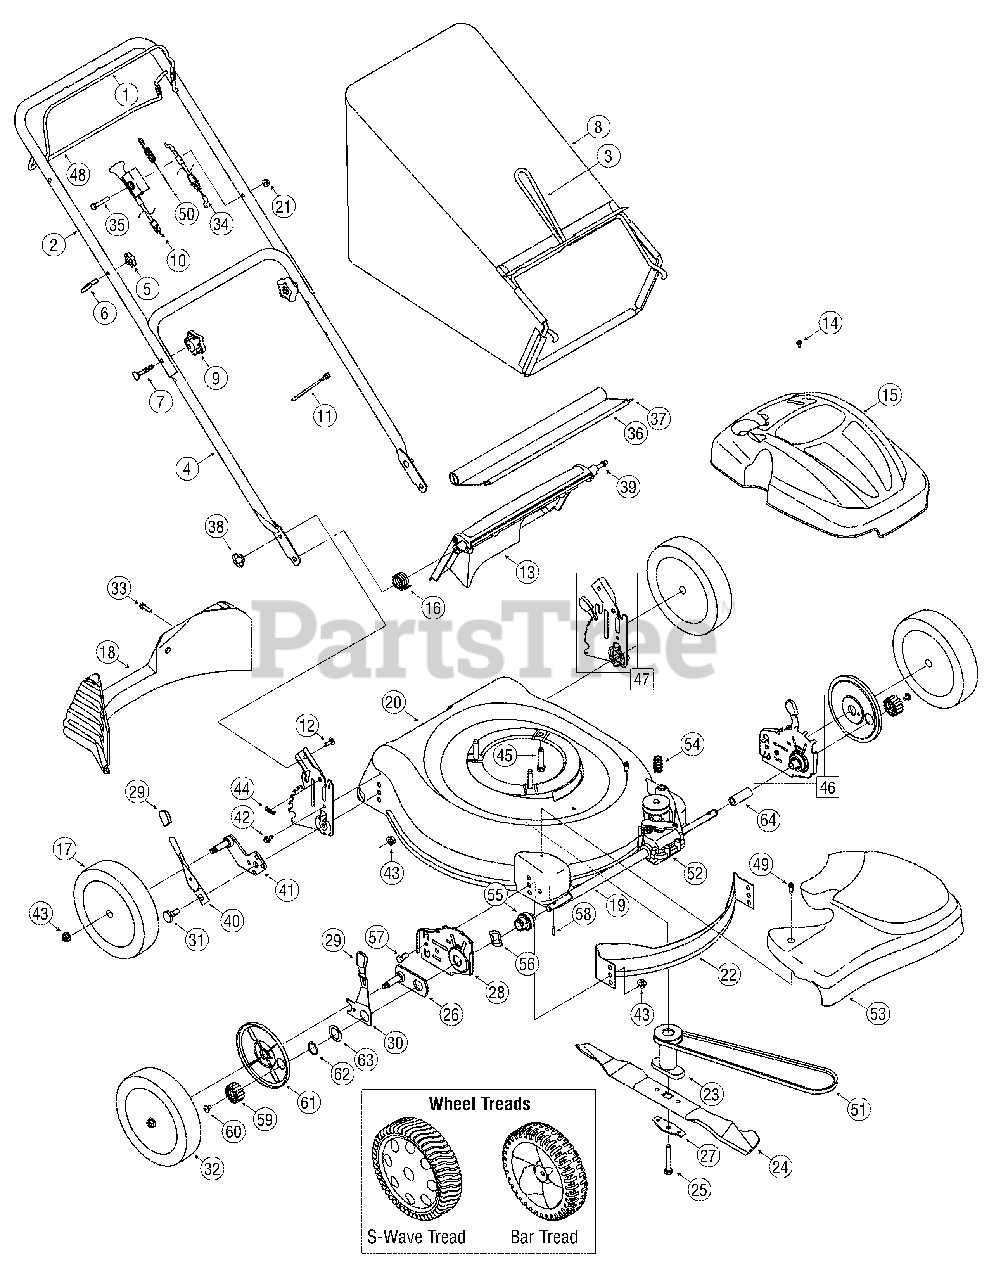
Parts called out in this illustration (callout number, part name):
5	Wing Nut
6	Rope Guide
7	Carriage Bolt ,5/16-18 x 2
8	Grass Bag Assembly
9	Star Knob
10	Choke Cable
11	Cable Tie
12	Carriage Bolt ,1/4-20
13	Rear Discharge Door
14	Screw, Machine, M-4 x 10
15	Engine Shroud
16	Torsion Spring - RH
17	Rear Wheel, 8 x 1.8, Bar
18	Rear Baffle
19	Sleeve Spacer - RH
21	Flange Lock Nut, 1/4-20
22	Front Baffle
23	Blade Adapter w/Pulley
24	21" Mulching Blade
25	Hex Bolt , 3/8-24 x 2.5
26	Pivot Plate Assembly
27	Blade Bell Support
28	Height Adjustment Plate - RH
28	Height Adjustment Plate - LH
29	Adjustment Lever Knob
30	Front Lever - RH
30	Front Lever - LH
31	Shoulder Screw
32	Front Wheel, 8 x 1.8, Bar
33	Screw, 1/4-15 x 1.000
34	Control Cable - 48"
35	Screw, 1/4-20 x 1.50
36	Trailshield
37	Trailshield Wire
38	Wing Nut, 1/4-20
39	Rear Door Pivot Rod
40	Spring Lever
41	Pivot Arm Assembly - RH
41	Pivot Arm Assembly - LH
42	AB Screw
43	Flange Lock Nut, 3/8-16
44	Hairpin Clip
45	TT Sems Screw, 3/8-16 x 1.00
46	Ht. Adj. Assy. Front - LH
46	Ht. Adj. Assy. Front - RH
47	Rear Handle Bracket Assy. - LH
47	Rear Handle Bracket Assy. - RH
48	Drive Control
49	Shoulder Screw
50	Drive Cable
51	V-Belt
52	Transmission Assembly
53	Front Drive Cover
54	Belt Tension Spring
55	Bearing Assembly
56	Wave Washer
57	Hex Screw
58	Dowel Pin
59	Gear, 14T - RH
59	Gear, 14T - LH
60	Screw, 1/4-20 x .390
61	Wheel Dust Cap
62	Snap Ring
63	Washer, 1.5" OD
64	Sleeve Spacer - LH
